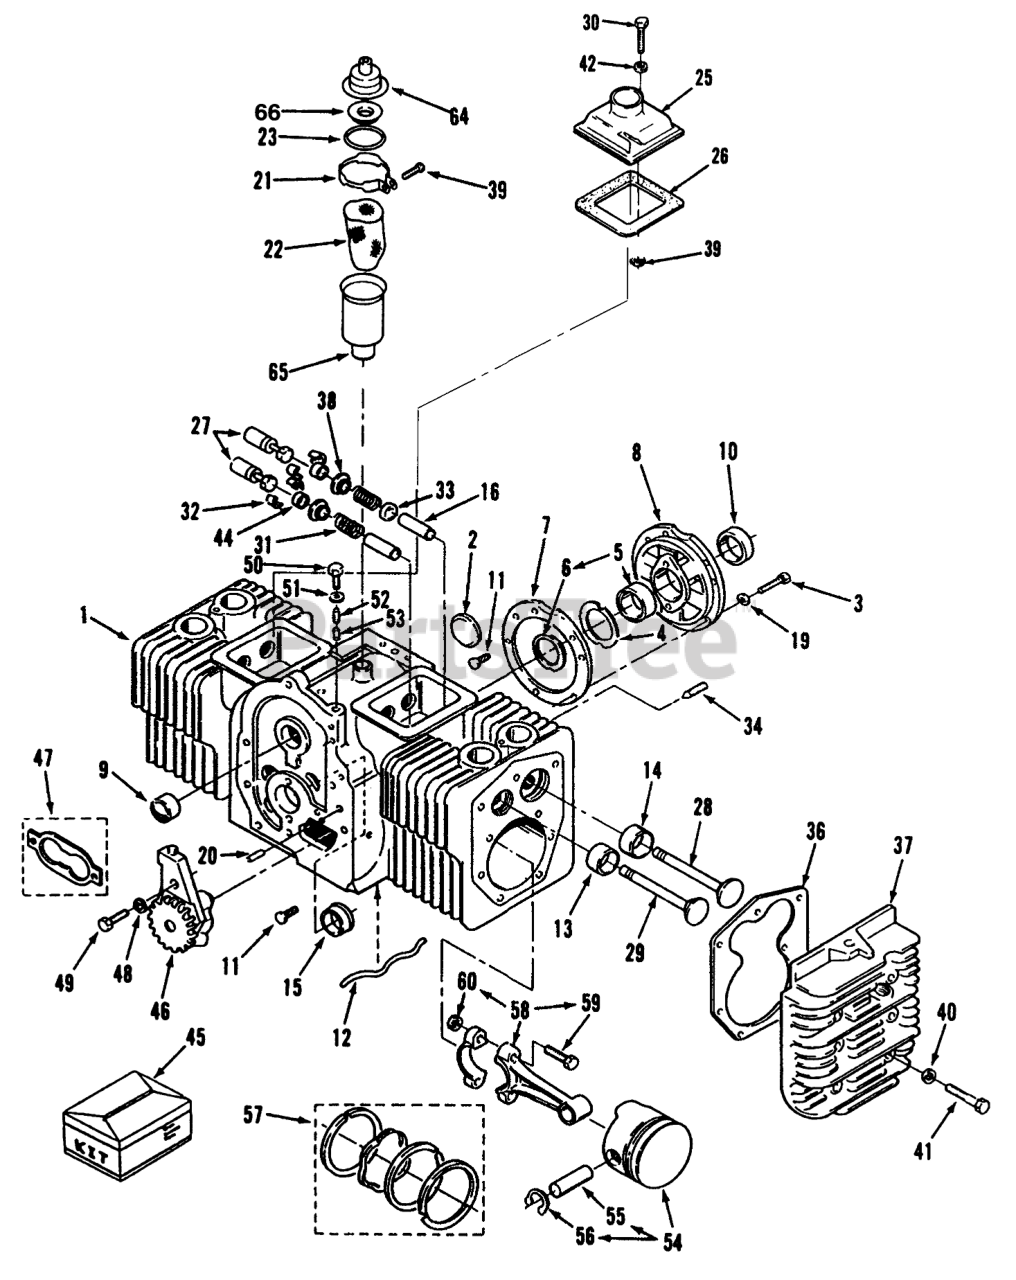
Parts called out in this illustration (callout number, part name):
1	CYLINDER BLOCK
3	HEX HD CAPSCREW
5	BEARING KIT (STANDARD SLEEVE)
6	WASHER
7	Gasket
8	PLATE-BEARING, REAR
9	WASHER
10	SLEEVE-BEARING
11	Screw
12	OIL TUBE
13	Standard
14	Standard
15	Standard
16	Guide-ExhaustValve
19	Washer
20	Pin
21	Clamp
22	FILTER
23	SEAL - O-RING
25	VALVE-COVER L.H.
26	GASKET
27	Tappet
28	Intake Valve
29	Intake Valve
30	HHCS 1/4-20 X 1 3/4
31	Spring
32	VALVE SPRING LOCK
33	Seal
34	Screw
36	Gasket
37	Right Side
38	Washer
39	SCREW-TAPPING, ROUND HEAD
40	WASHER
41	Bolt
42	Washer
44	VALVE CAP
45	ENGINE GASKET KIT
46	Oil Pump
47	Oil Pump Gasket Kit
48	WASHER-FLAT
50	SCREW-HH
51	Washer
52	Spring
53	Piunger
54	Standard
55	Pin-Piston
56	Retaining Ring
57	RING/PISTON KIT
58	CONNECTING ROD W/NUT
59	Rod Bolt
60	Nut
64	BREATHER-CAP AND VALVE
65	TUBE-BREATHER
66	SCREEN-BREATHER TUBE
